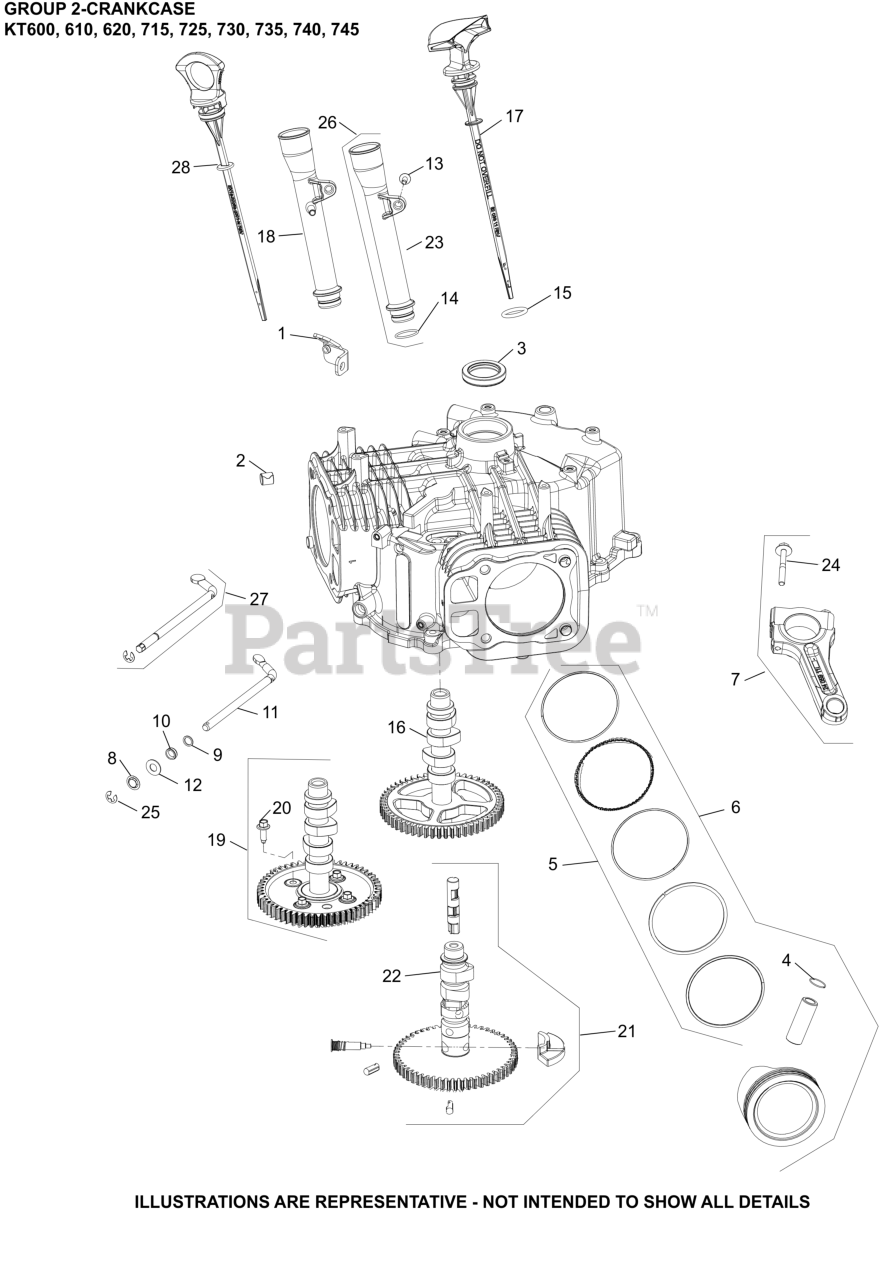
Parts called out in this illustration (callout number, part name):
1	BRACKET, OIL FILL TUBE
2	PIN, LOCATING
3	SEAL, OIL (HELIX LIP)
4	RETAINER, PISTON PIN
6	KIT, PISTON 725CC (STD) STYLE B
7	ROD, ASSEMBLY CONNECTING
9	WASHER, FLAT 11/32"
10	SEAL, GOVERNOR CROSS SHAFT
12	WASHER, FLAT 9 MM
16	CAMSHAFT ASSY
17	DIPSTICK, ASSY
18	TUBE ASSEMBLY, OIL FILL
25	CLIP, RETAINER GOVERNOR SHAFT
27	KIT, CROSS SHAFT
